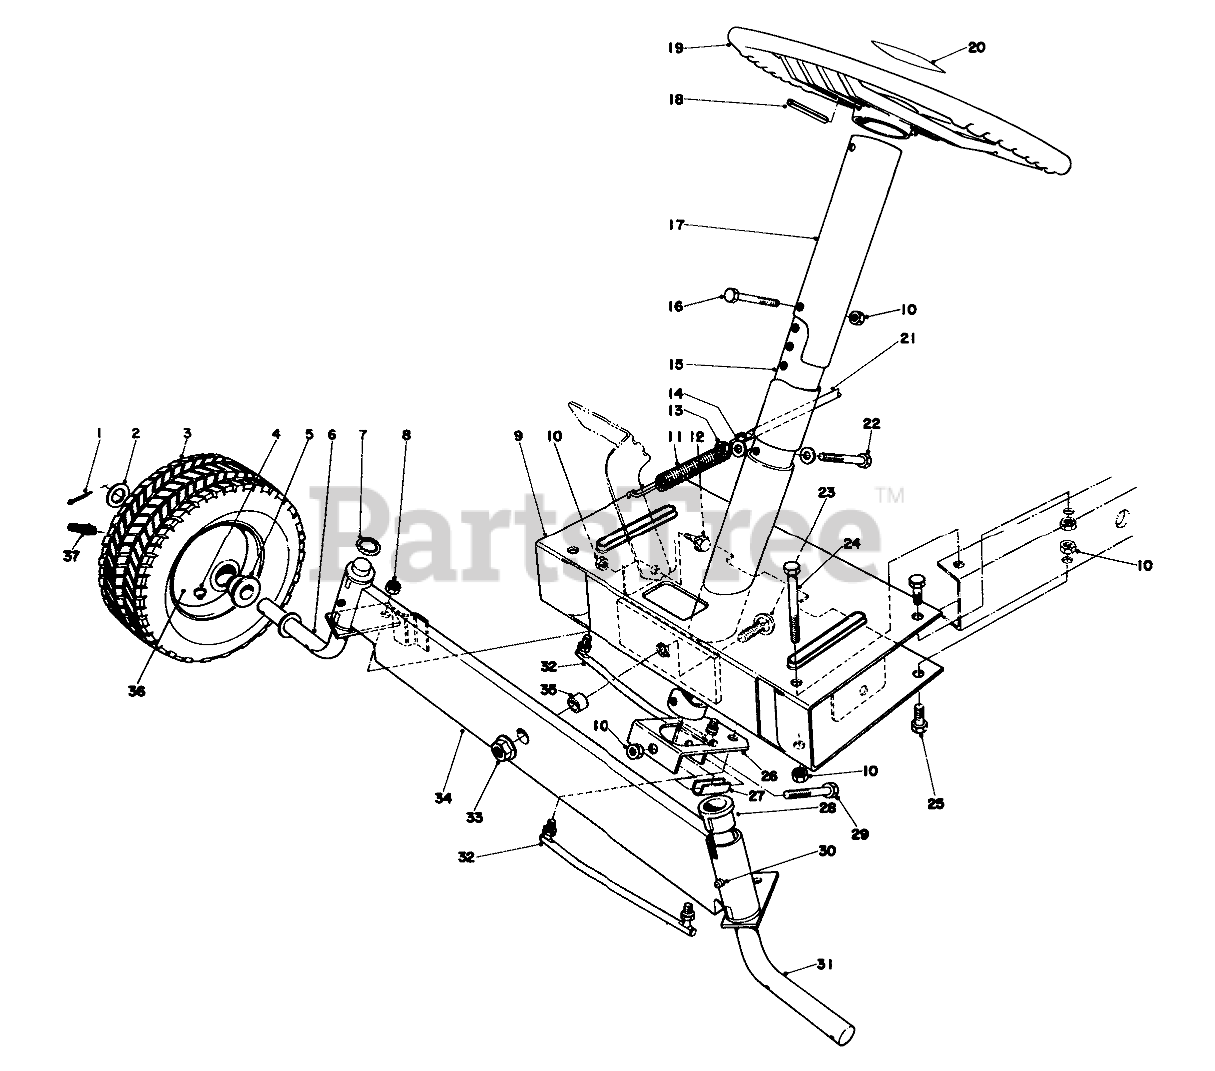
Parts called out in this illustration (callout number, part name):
1	PIN-COTTER
2	WASHER-FLAT
3	Tire Turf King
4	FITTING-GREASE
5	BUSHING
6	SPINDLE WA RH
7	RING-RETAINING
8	NUT-LOCK NI
9	Front Frame
10	NUT-LOCK, CONE
11	Brake Spring
12	SCREW-SHOULDER
13	NUT-LOCK, CONE
14	WASHER-FLAT
15	Steering Tube Inner
16	SCREW-HH
17	Steering Tube Outer
18	PIN-ROLL
19	Steering Wheel
20	Decal
21	Brake Rod
22	SCREW-HH
23	SCREW-CARR
24	SCREW-HH
25	SCREW-HH
26	Lever Steering
27	Spacer-Steering Tube
28	BUSHING
29	SCREW-HH
30	GREASE FITTING
31	Spindle L.H.
32	TIE ROD ASM
33	NUT-HF
34	Front Axle
35	FRONT AXLE SPACER
37	STEM-VALVE
